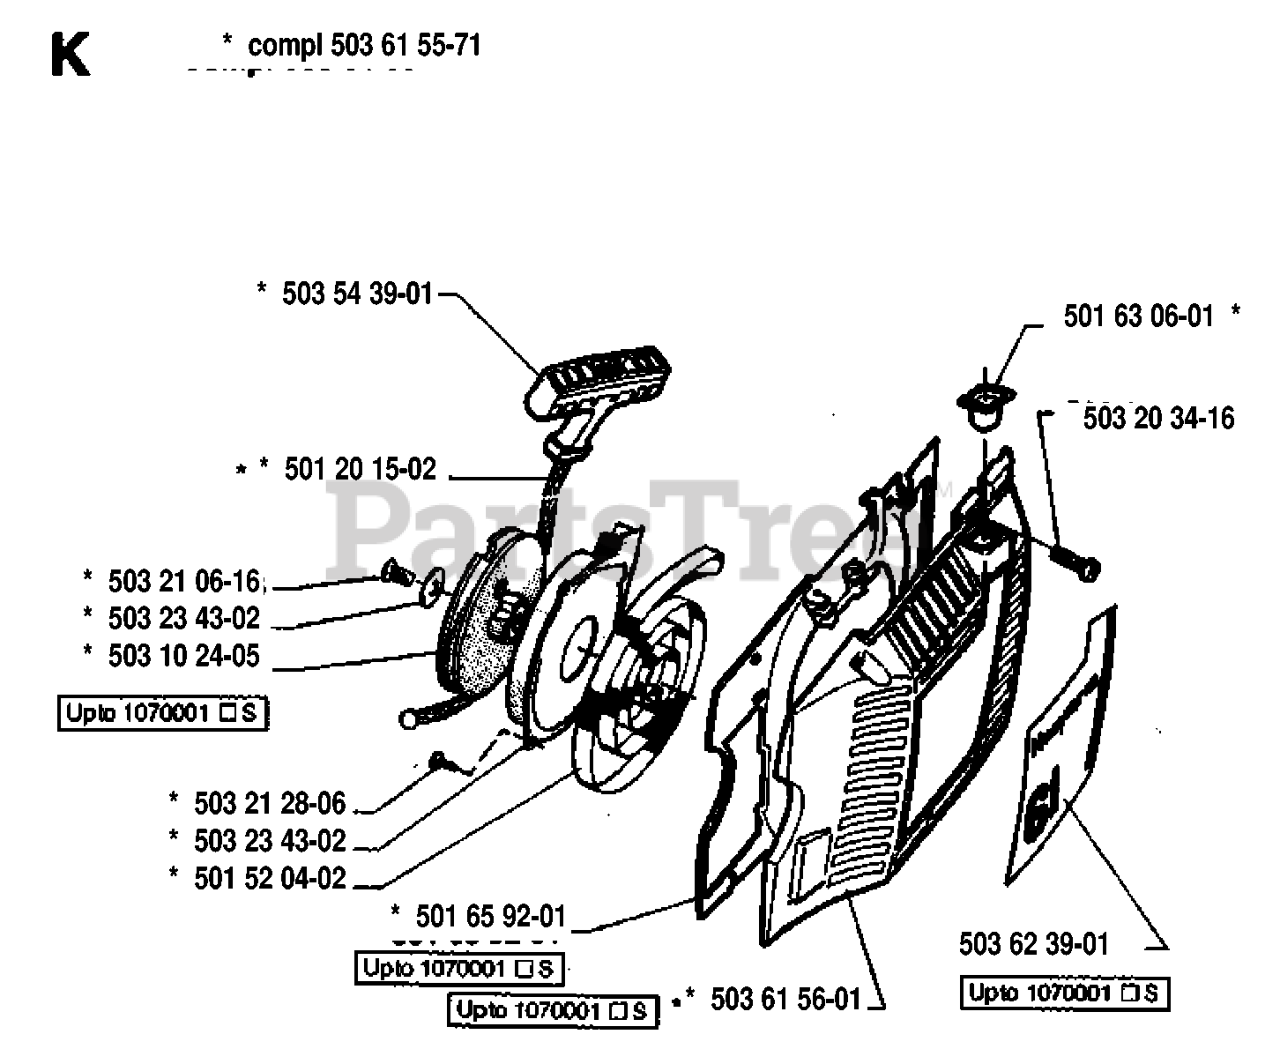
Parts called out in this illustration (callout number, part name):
1	DECAL FENDER DANGER
3	HOOD DECAL LH
4	HOOD DECAL RH
5	DECAL HP ENGINE
6	DECAL DRAWBAR CONTROL
8	DECAL WARNING (ENGLISH/FRENCH)
9	DECAL FENDER HUSQ
10	DECAL FENDER DANGER
14	DECAL V-BELT SCHEMATIC
20	DECAL, BATTERY DANGER
